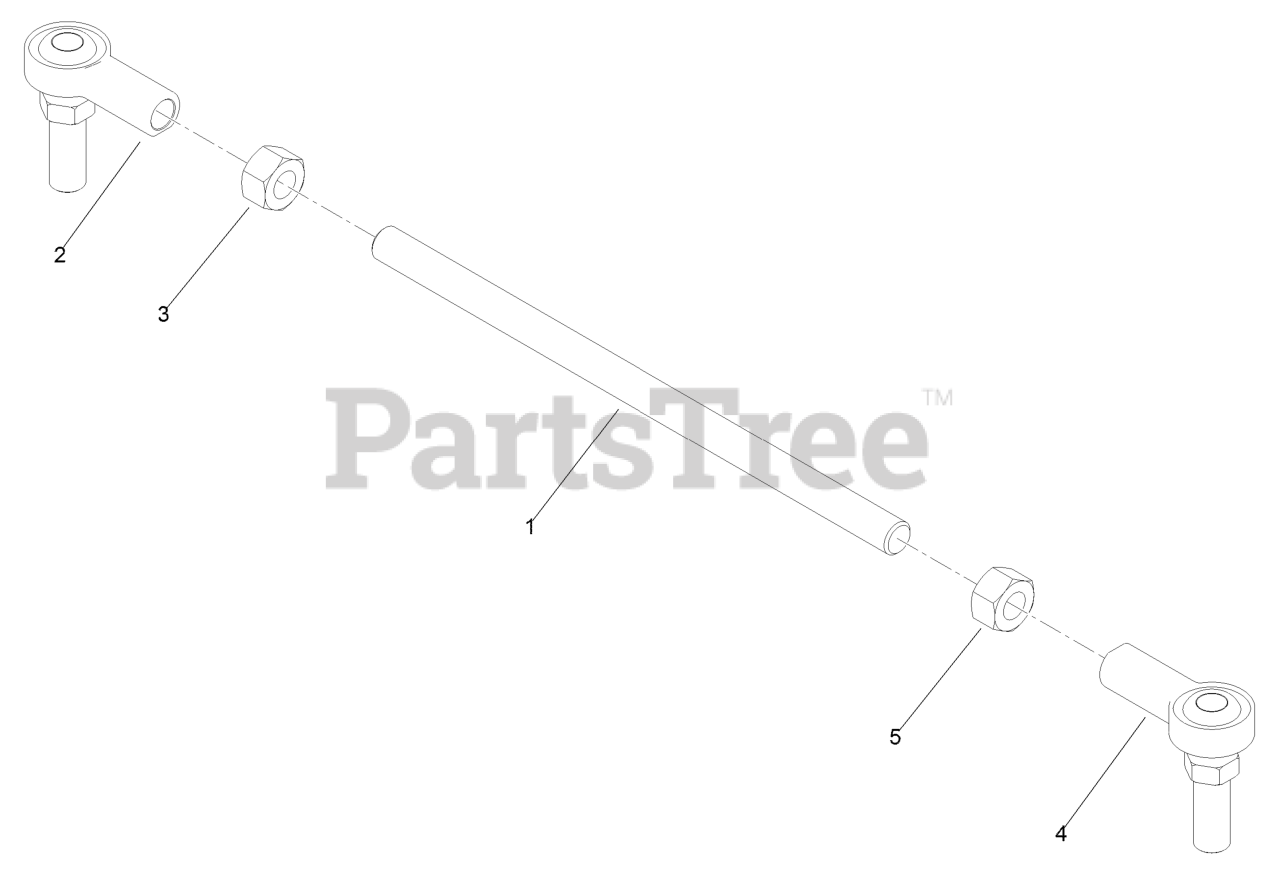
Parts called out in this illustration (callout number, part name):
1	ROD-LINKAGE, STEERING
2	ROD-END, RH
3	NUT-HEX
4	ROD-END, LH
5	NUT-HEX, LH
